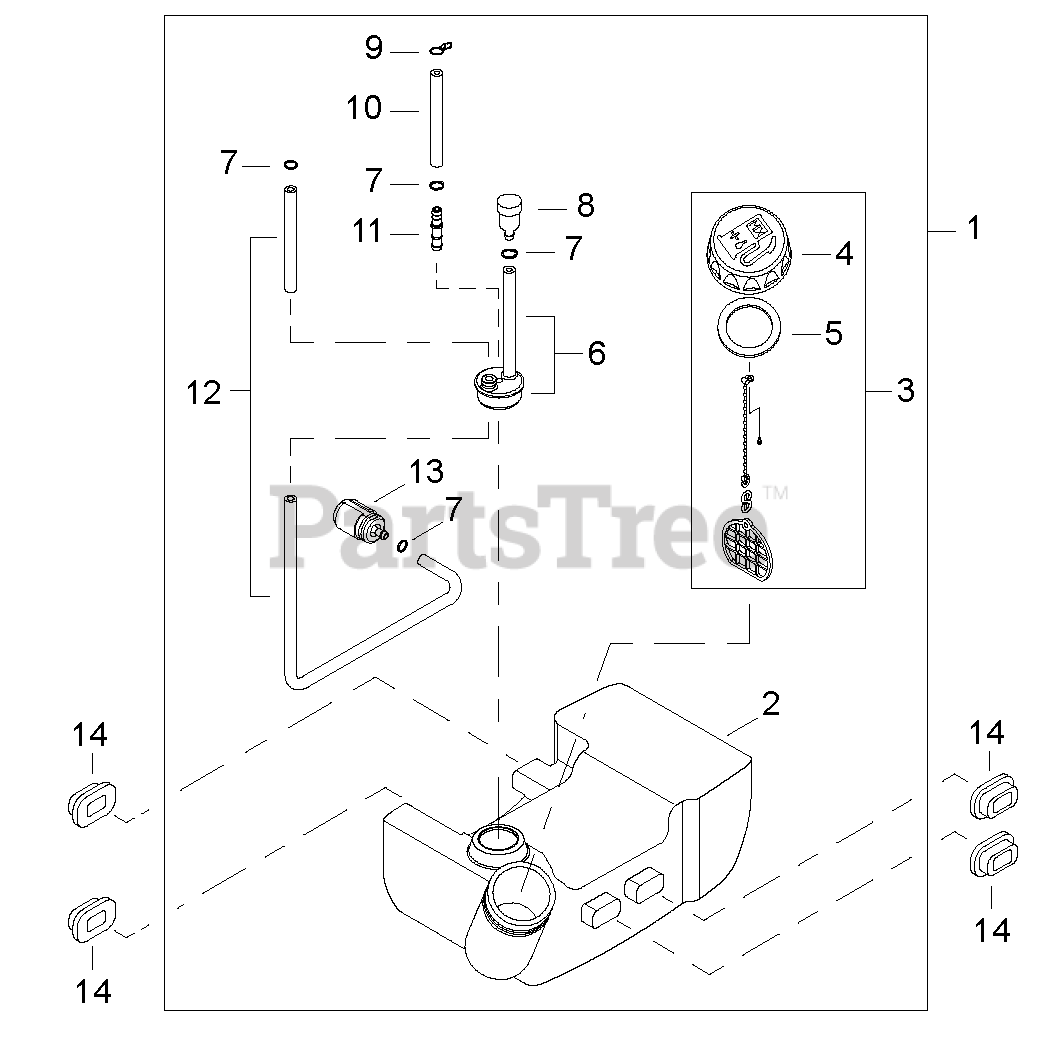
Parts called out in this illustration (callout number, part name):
1	TANK ASSY, FUEL
2	TANK, FUEL
3	CAP ASSY, FUEL
4	CAP, FUEL
5	GASKET, FUEL CAP
6	GROMMET, FUEL W/VENT PIPE
7	CLIP Ø6
8	VENT ASSY
9	CLIP, SPRING Ø5.2
10	PIPE, FUEL RETURN L= 52.5 MM
11	CONNECTOR, PIPE
12	PIPE, FUEL 3.3×6×160
13	FILTER, FUEL 125-528
14	CUSHION, FUEL TANK
